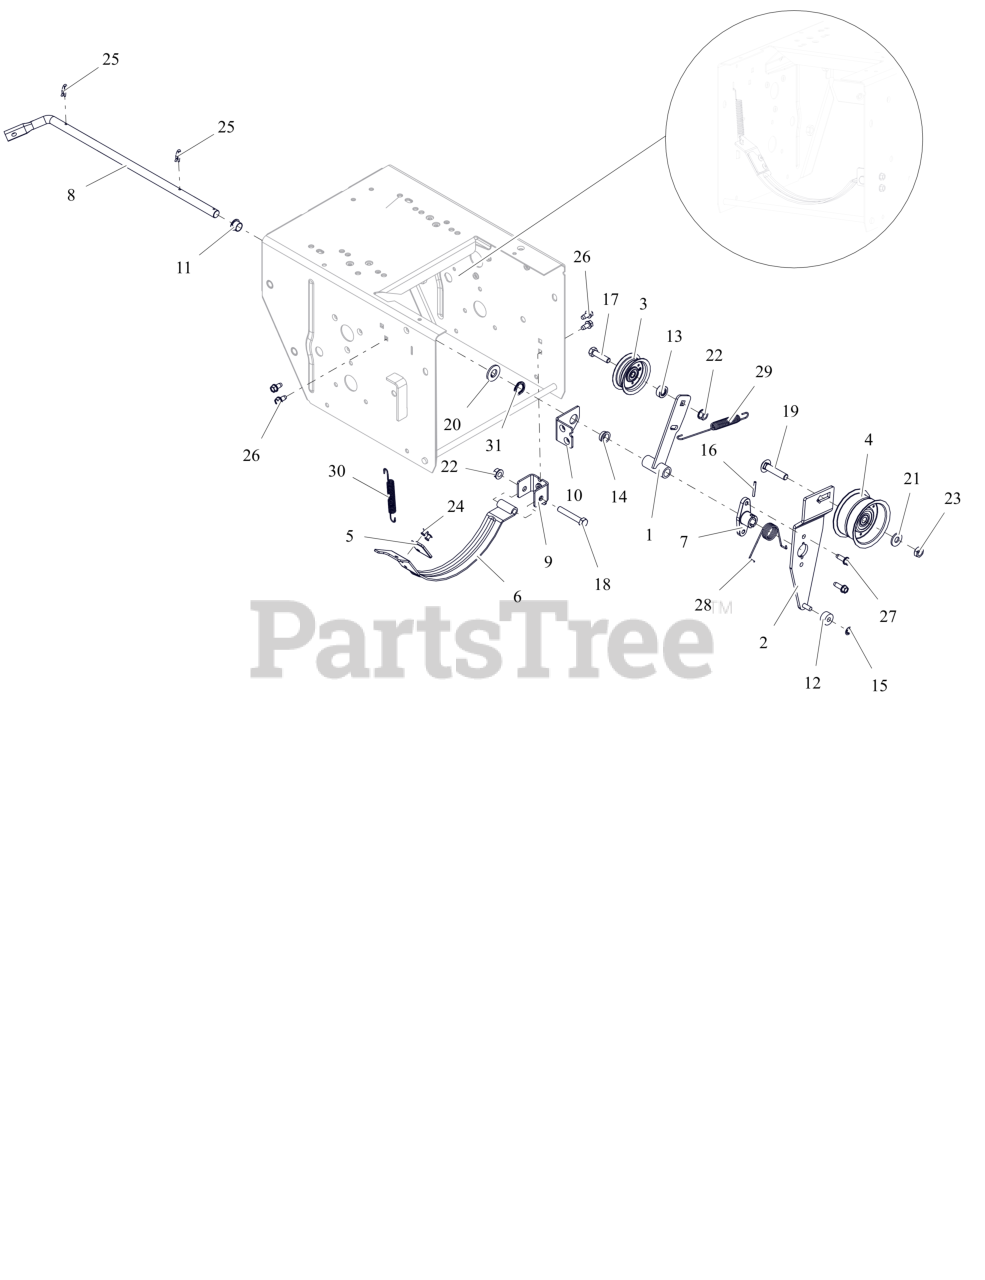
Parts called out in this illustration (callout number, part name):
1	ARM, IDLER-TRACTION
2	ARM, IDLER - ATTACHMENT
3	IDLER, FLAT - 2.00"
4	IDLER, FLANGE -2.75 OD X .375 ID
5	PAD, BRAKE
6	ARM, BRAKE-ATTACHMENT
7	HUB, BRAKE ARM
8	ARM, ATTACHMENT
9	PIVOT, BRAKE
10	BRACKET, SUPPORT
11	BUSHING, POLYLINER-.50 SPLIT
12	BSHG,SLV .265 X .625 X .375
13	SPCR, BRG .315X.500X.358X.281
14	BSHG,FLANGE .500X.625X.270X.75
15	RG-RTNG-EXT .250X.010
16	PIN-ROLL .125X1.00
17	BLT, HEX .31-18X1.25 G5 ZCC
18	BLT, HEX .31-18X2.00 G5 ZCC
19	BLT, RHSSN .38-16X1.75 G5 ZCC
20	WSHR,FLT .531X1.062X.095 ZCC
21	WSHR,FLT .375X.875X.083 ZCC
22	NUT-LK-TOP-FLG .312-18 GF ZCC
23	NUT-LK-CTR-JAM .375-16 GB ZCC
24	RVT, POP .1875 ZCC
25	CLIP, SPRING
26	SCR-TAP .25-20X.50 HWH ZCC
27	SCR,TAP .25-20X.75 HWH TR ZCC
28	SG-TORS .067X.88
29	SG-TENS .06X.482X5.35
30	SPRING-EXT .437 X .438 X 2.64
31	WAVE SPRING .600X.875X.25FH
